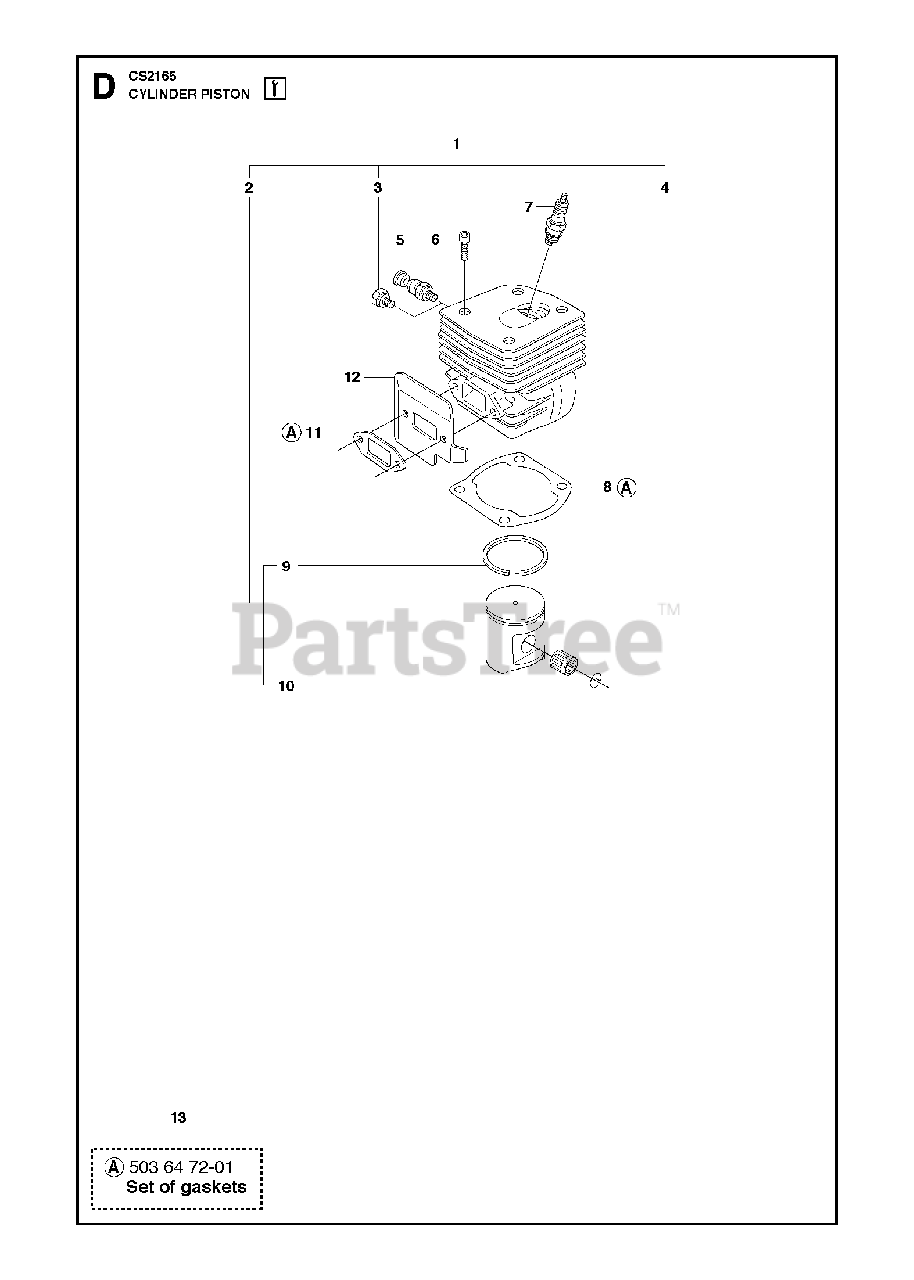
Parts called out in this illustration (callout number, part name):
1	CYLINDER
2	PISTON CPL 48 MM
3	CYLINDER PLUG
4	SUPPORT BUSHING
5	DECOMPRESSION VALVE
6	SCREW MC6S 5X25
7	SPARK PLUG RCJ7Y
8	GASKET
9	PISTON RING
11	GASKET
12	DEFLECTOR
13	GASKET SET
